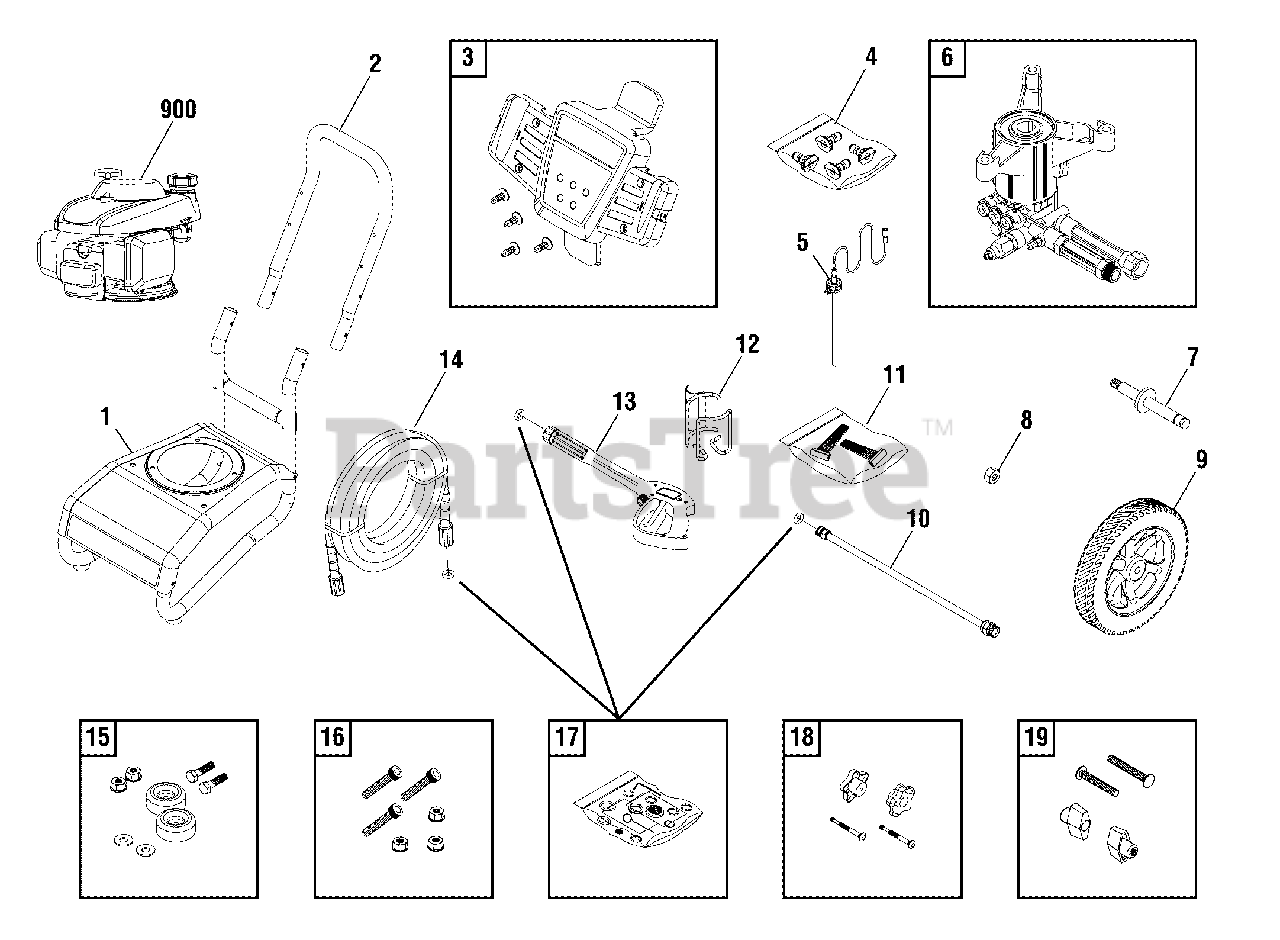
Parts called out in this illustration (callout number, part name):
1	BASE
10	EXTENSION, QC
13	GUN
14	HOSE
15	MOUNT, Vibration
16	KIT, Hardware, Pump Mounting
17	KIT, 0-Ring
900	** ENGINE
